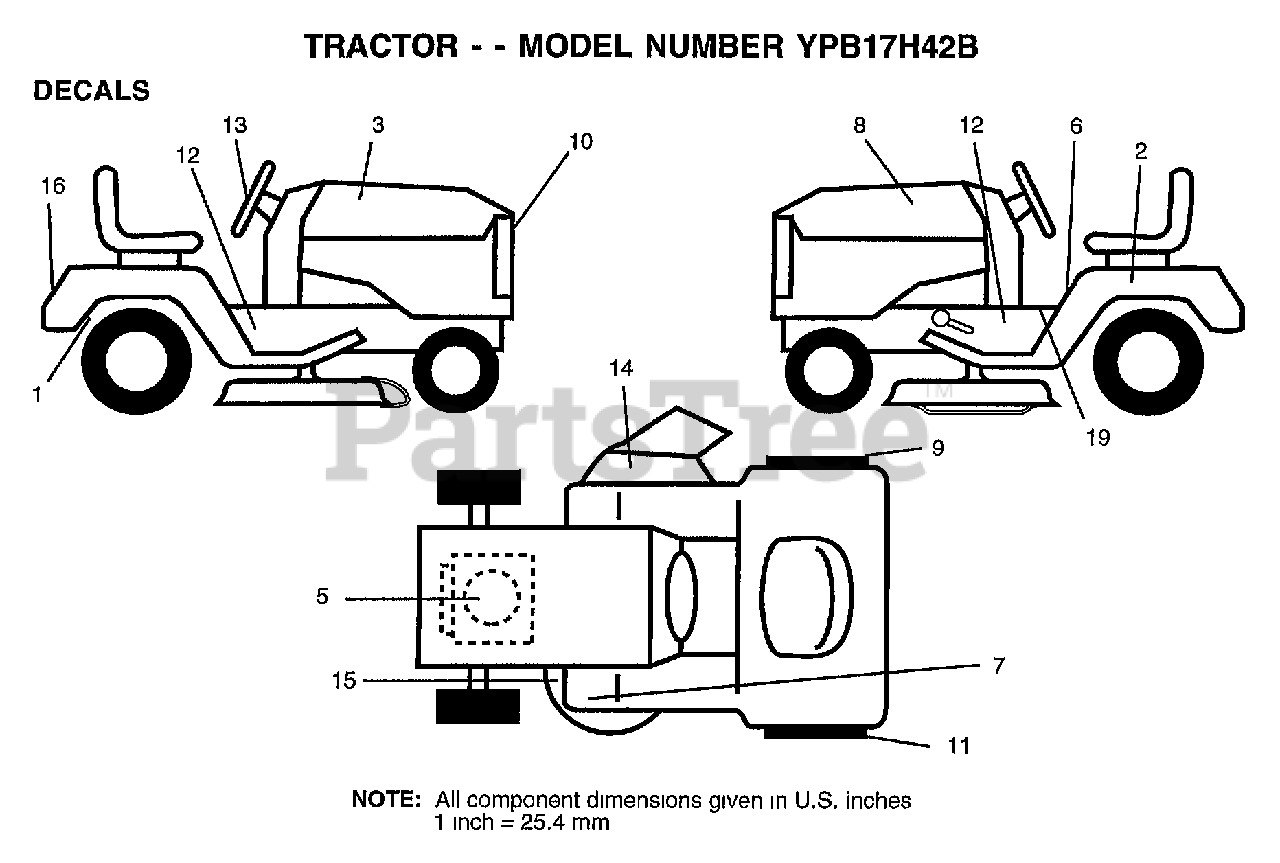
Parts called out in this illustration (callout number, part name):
1	DECAL BY PASS LT HYDRO
2	DECAL.BATRY.3-3908
3	DECAL.BATRY.3-3908
5	DECAL, HP ENGINE
6	DECAL.CAUT.ENG/FR
7	DECAL T
8	DECAL
9	DECAL FENDER RH
11	DECAL FENDER LH
12	DECAL CHASSIS
13	DECAL INS STRG WH
14	"DECAL, WARNING"
15	"DECAL-SCHEM,BELT"
16	DECAL FENDER
19	DECAL SADDLE OPER
